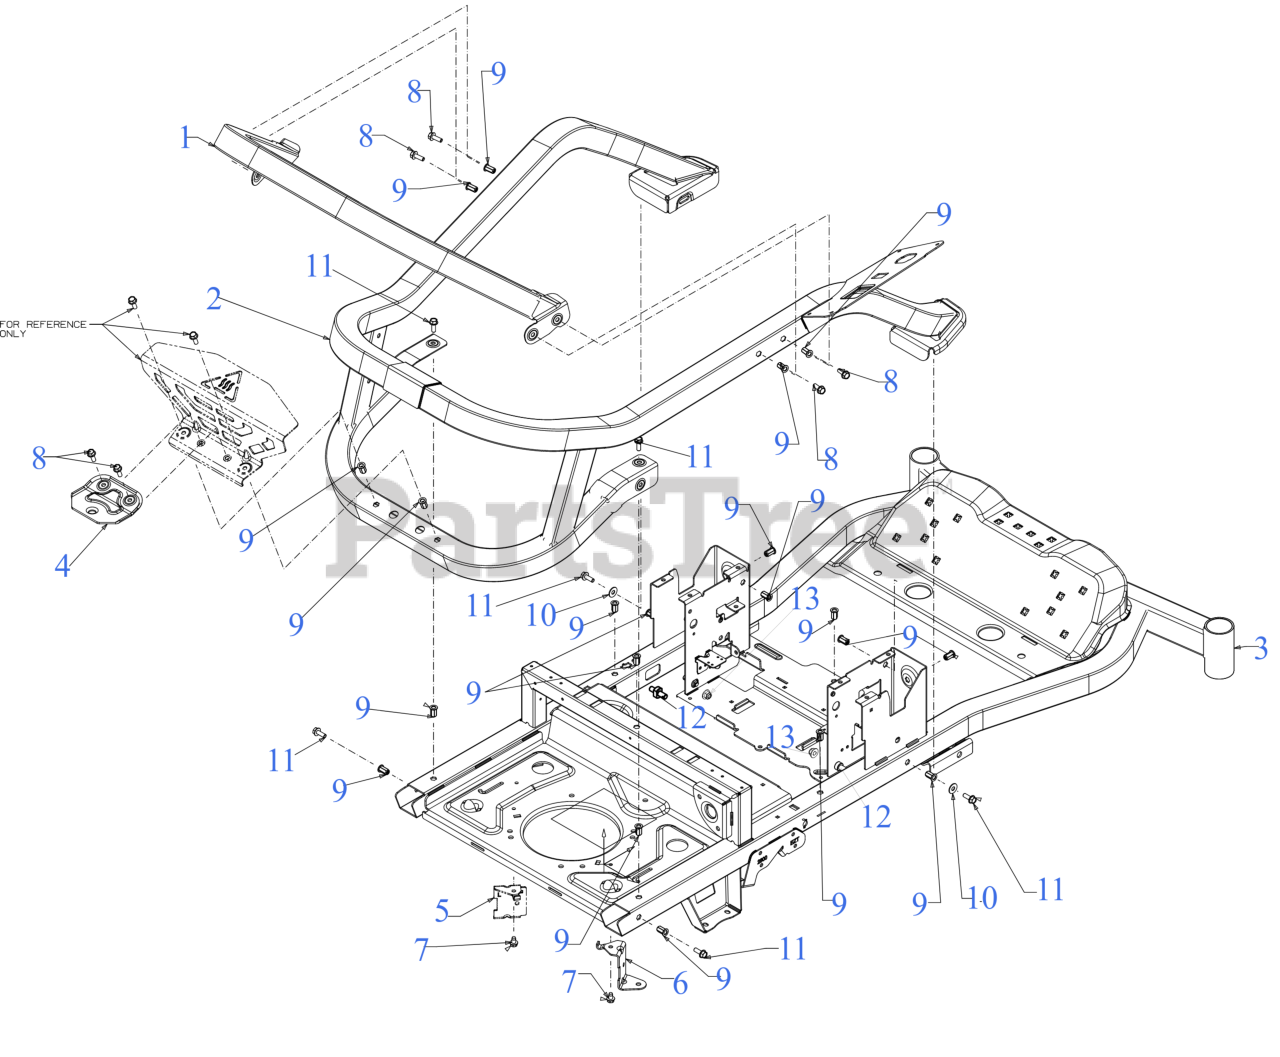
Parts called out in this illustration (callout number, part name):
1	UPPER FRAME HOOP
2	UPPER FRAME
3	FRAME
4	HITCH PLATE
5	TRANSMISSON MOUNT SUPPORT (LH)
6	TRANSMISSON MOUNT SUPPORT (RH)
7	SCREW 5/16-18 x .500
8	SCREW 5/16-18 x .875 GR5
9	NUT RIVET 5/16-18
10	FLAT WASHER
11	SCREW 5/16-18 x 1.25
12	SHOULDER STUD
